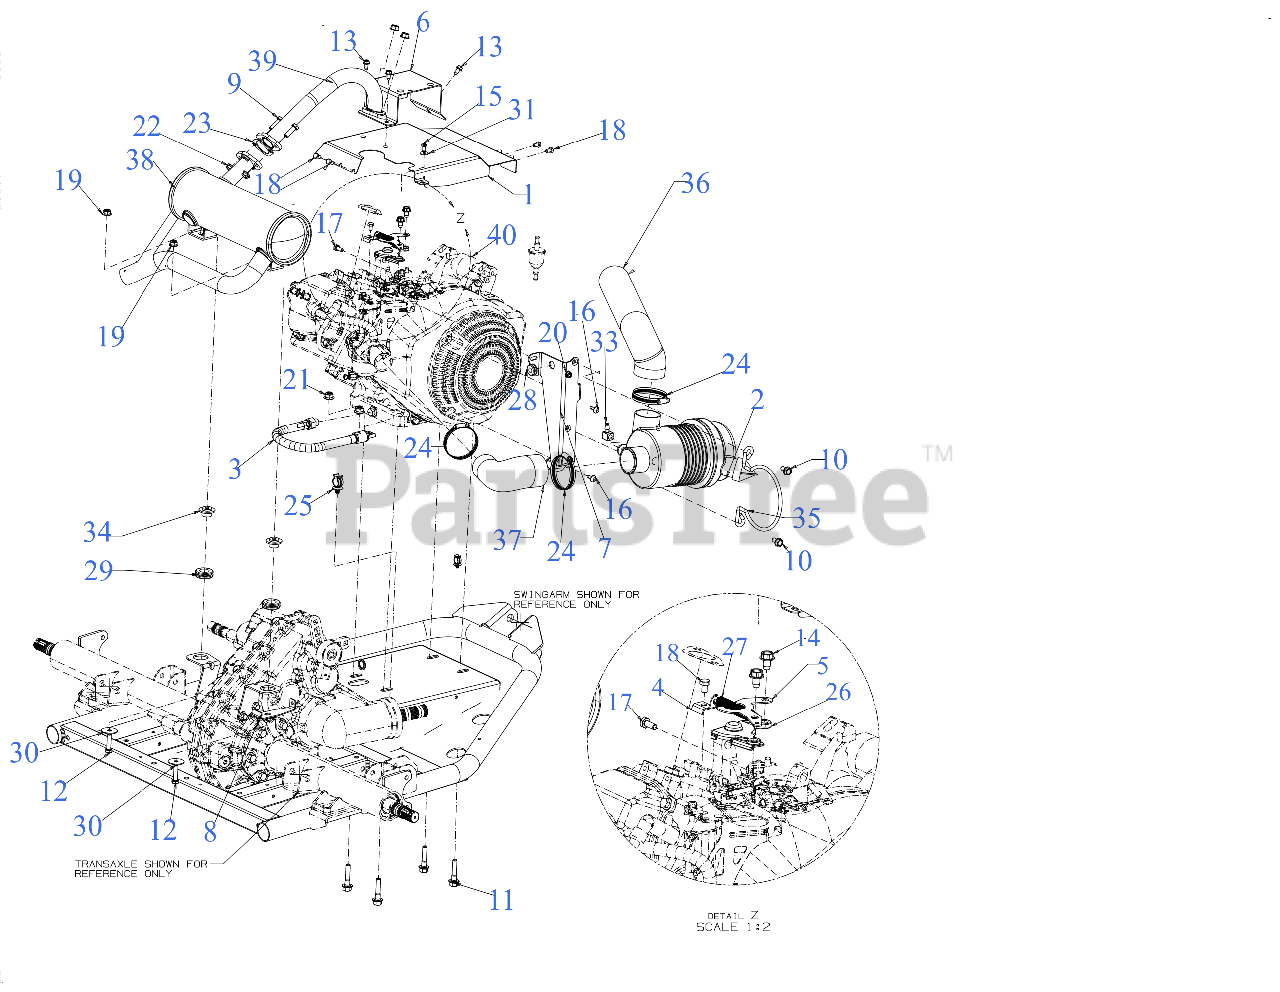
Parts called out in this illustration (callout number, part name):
1	ENGINE COVER ASSEMBLY
2	AIR CLEANER FILTER ASSEMBLY
3	OIL DRAIN HOSE ASSEMBLY M14-1.5MM
4	SPRING RETENSION BRACKET
5	THROTTLE MOUNTING BRACKET
6	AIR INLET COVER
8	THROTTLE MOUNTING BRACKET
9	SCREW 5/16-18 x 1.0 GR5
10	SCREW 5/16-18 x .750
11	SCREW 3/8-18 x 1.75 GR5
12	SCREW 5/16-18 x 1.25 GR5
13	SCREW 1/4-20 X.500
14	SCREW 5/16-18 x .500
15	SCREW M5-.8X10MM SLOT/TORX
16	SCREW M6-1 x .625
17	SCREW 1/4-20 x .620 GR5
18	SCREW M6-1.0X10MM GR8.8
19	FLANGE LOCK NUT 5/16-18
20	FLANGE LOCK NUT
22	FLANGE NUT
23	EXHAUST GASKET
24	ADJUSTABLE HOSE CLAMP 1.31-2.25"
25	DRAIN HOSE CLIP
26	CONTROL PANEL COVER
27	EXTENSION SPRING
29	GROMMET .75 x 1.063 x .4375
30	FLAT WASHER .322 ID x 1.25 x .060
33	90 DEGREE FITTING
34	SHOULDER SPACER .750 x .145
35	AIR FILTER STRAP ROD
36	AIR INLET HOSE
37	AIR FILTER INTAKE HOSE
39	EXHAUST PIPE
40	COMPLETE ENGINE LTV
